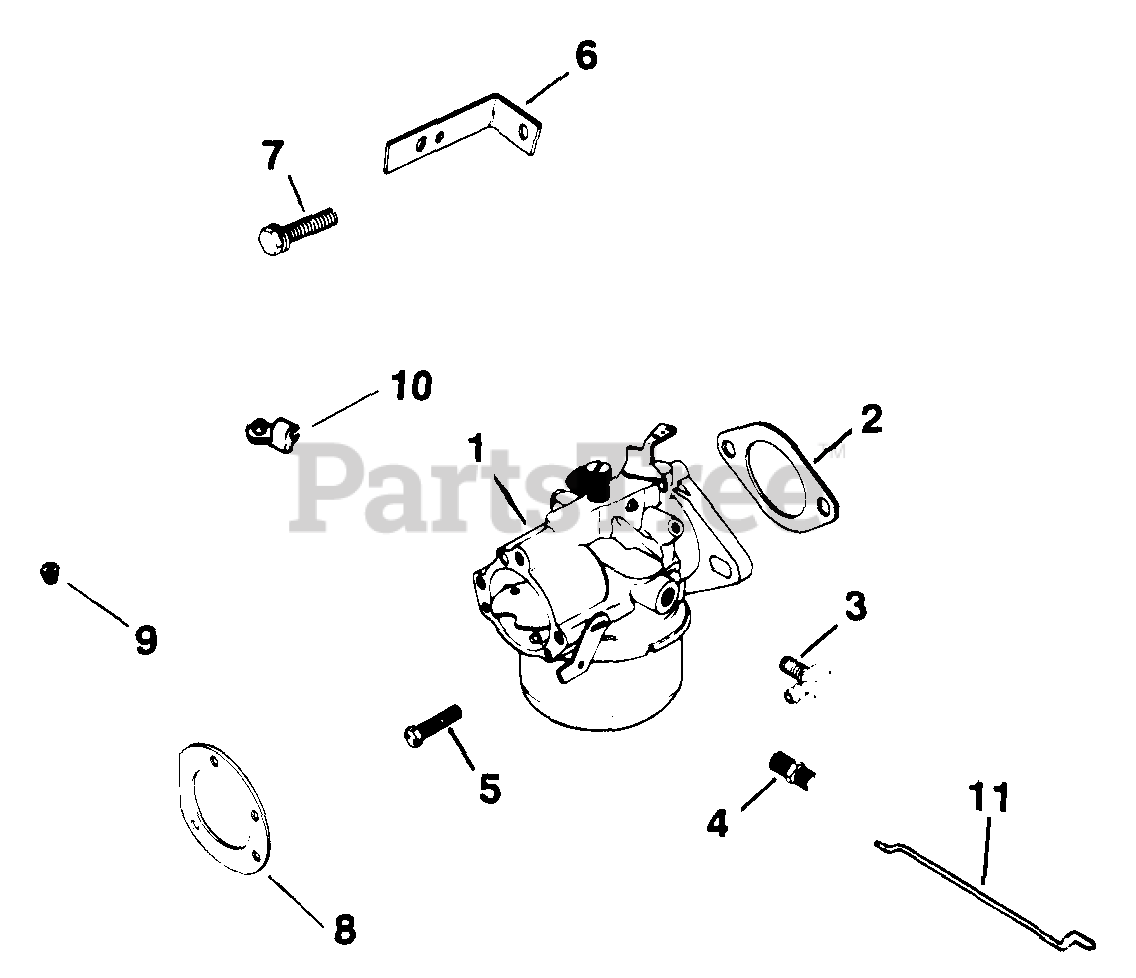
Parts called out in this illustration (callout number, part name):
1	CARBURETOR - USE 41 853 07
1	KIT,CARBURETOR - DISCONTINUED
3	CONNECTOR, 90 DEG. HOSE
5	SCREW-DISCONTINUED
6	BRACKET, CHOKE - (#DSC)
7	SCREW, SEMS 1/4-20X5/8" USE 25 086 539-S
9	BUSHING, LINKAGE RETAINING
10	BUSHING - USE 25 158 11
